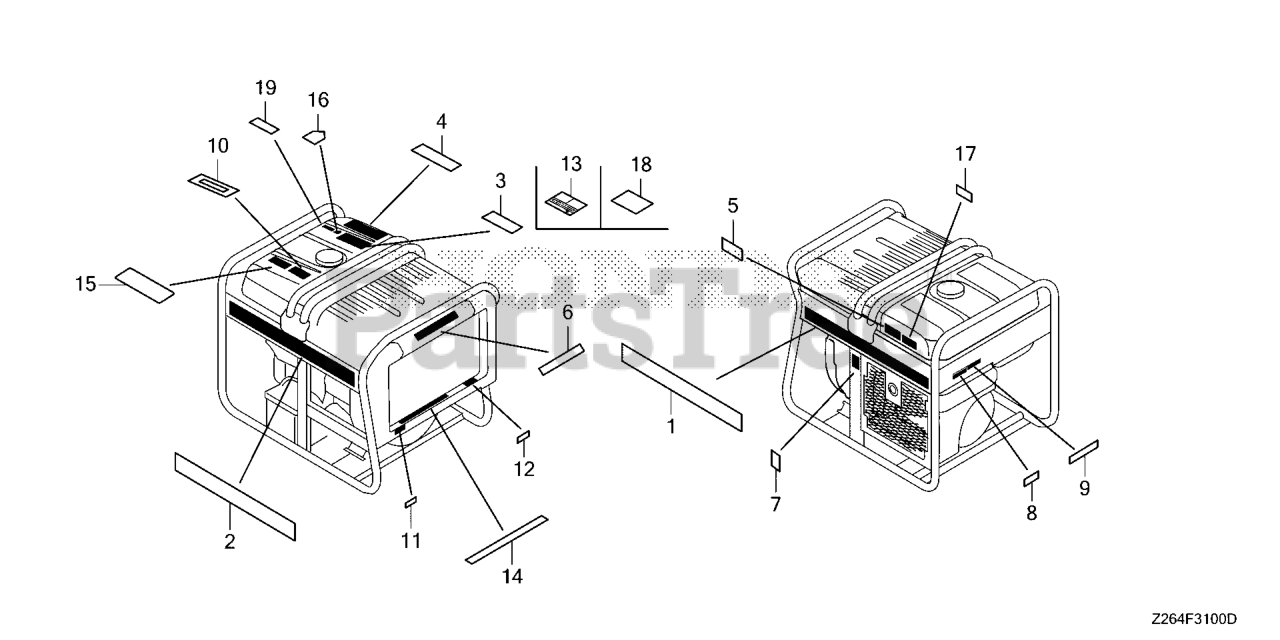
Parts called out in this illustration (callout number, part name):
1	MARK, R. EMBLEM (EB10000)
2	MARK, L. EMBLEM (EB10000)
4	MARK, CAUTION (AG)
5	MARK, SPECIFICATION (AN)
6	MARK, HONDA
7	MARK, EX. CAUTION (A)
8	MARK, EX. CAUTION
10	PLATE, FUEL INDICATION
11	MARK, FUEL PETCOCK
13	MARK, CPSC (CO CAUTION)
15	LABEL, FUEL WARNING (ENGLISH)
16	MARK, DIRECTION (AG)
17	LABEL, TAMPER PROOF (AG)
18	LABEL, SHUTOFF CAUTION (AG)
19	LABEL, WARNING
